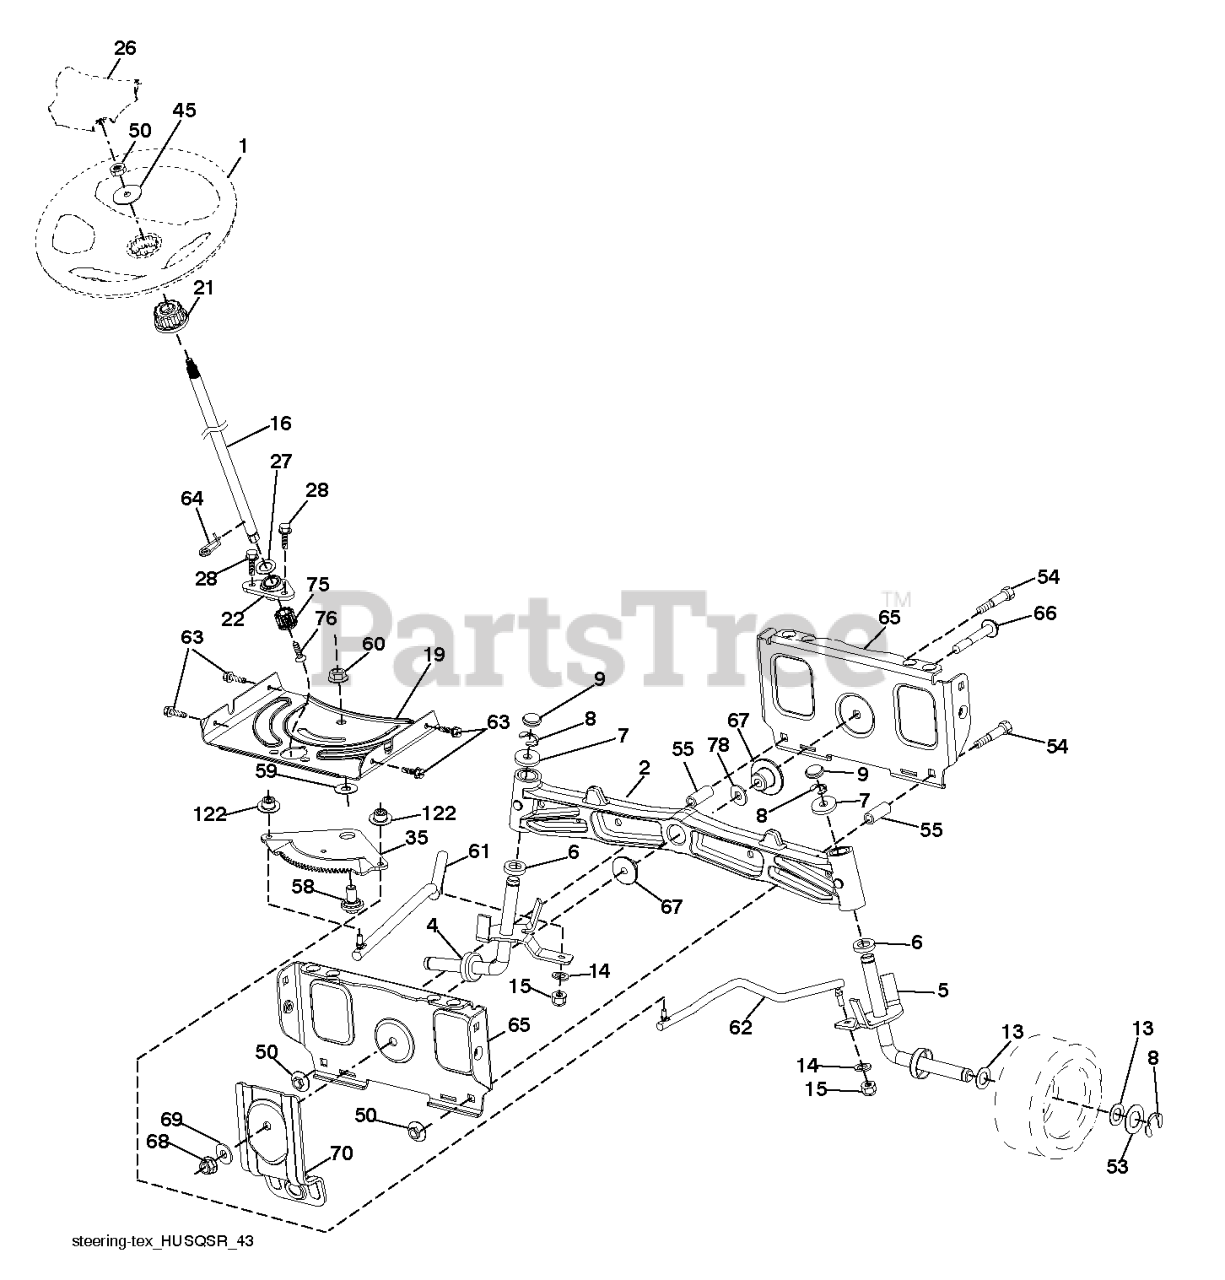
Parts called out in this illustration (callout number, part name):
1	WHEEL.STEER.HUSQ.SR.498.OVMLD
2	AXLE.CAST.IRON
4	SPINDLE.WELDED.LH.16"TEX
5	SPINDLE.WELDED.RH.16"TEX
6	THRUST WASHER
9	CAP.SPINDLE.BLACK
14	WASHER, LOCK 3/8
15	NUT CROWNLOCK 3/8-24
16	SHAFT.STEER.2HIGH.SPLND.PLATED
19	PLATE.STEER.DDL.NLT/NG
21	ADAPTER.WHEEL.STEER.SPLND.ALUM
22	BEARING.SUBASM.SHAFT.STEER.LOW
26	INSERT.CAP.WHL.STRG.HUSQ.PREM
27	WASHER LT
28	SCREW, 3/8-16X3/4
35	GEAR.SECTOR.PLATE.DDL.
45	WASHER.3/8ID.2-3/8OD.12GA.PLTD
50	NUT LOCK FLG 3/8-16 UNC
53	WASHER.HARDENED
55	SPACER.BRACE.AXLE
58	BOLT.SHOULDER.SECTOR.P
59	WASHER.THURST.SECTOR.S
60	NUT FLANGE LOCK 5/8-11
61	DRAGLINK.LH.BALLSTUD.D
62	DRAGLINK.RH.BALLSTUD.D
63	SCREW
64	RETAINER.CLIP.SPRING.S
65	BRACE.AXLE.FRONT.NLT/N
66	BOLT HEX FGHD 7/16-14 X 3 SERR
67	BUSHING.PM.FRONT AXLE
68	NUT.LOCK.FLANGE.7/16
69	WASHER.1.5X.505X.118
70	BRACKET.FRT.DECK.SUSP.RR.MT431
75	PINION.ZINC PLATED
76	SCREW HEAD SOCKET LRVB
78	THRUST WASHER
122	CAP.GEAR.SECTOR.TEX
